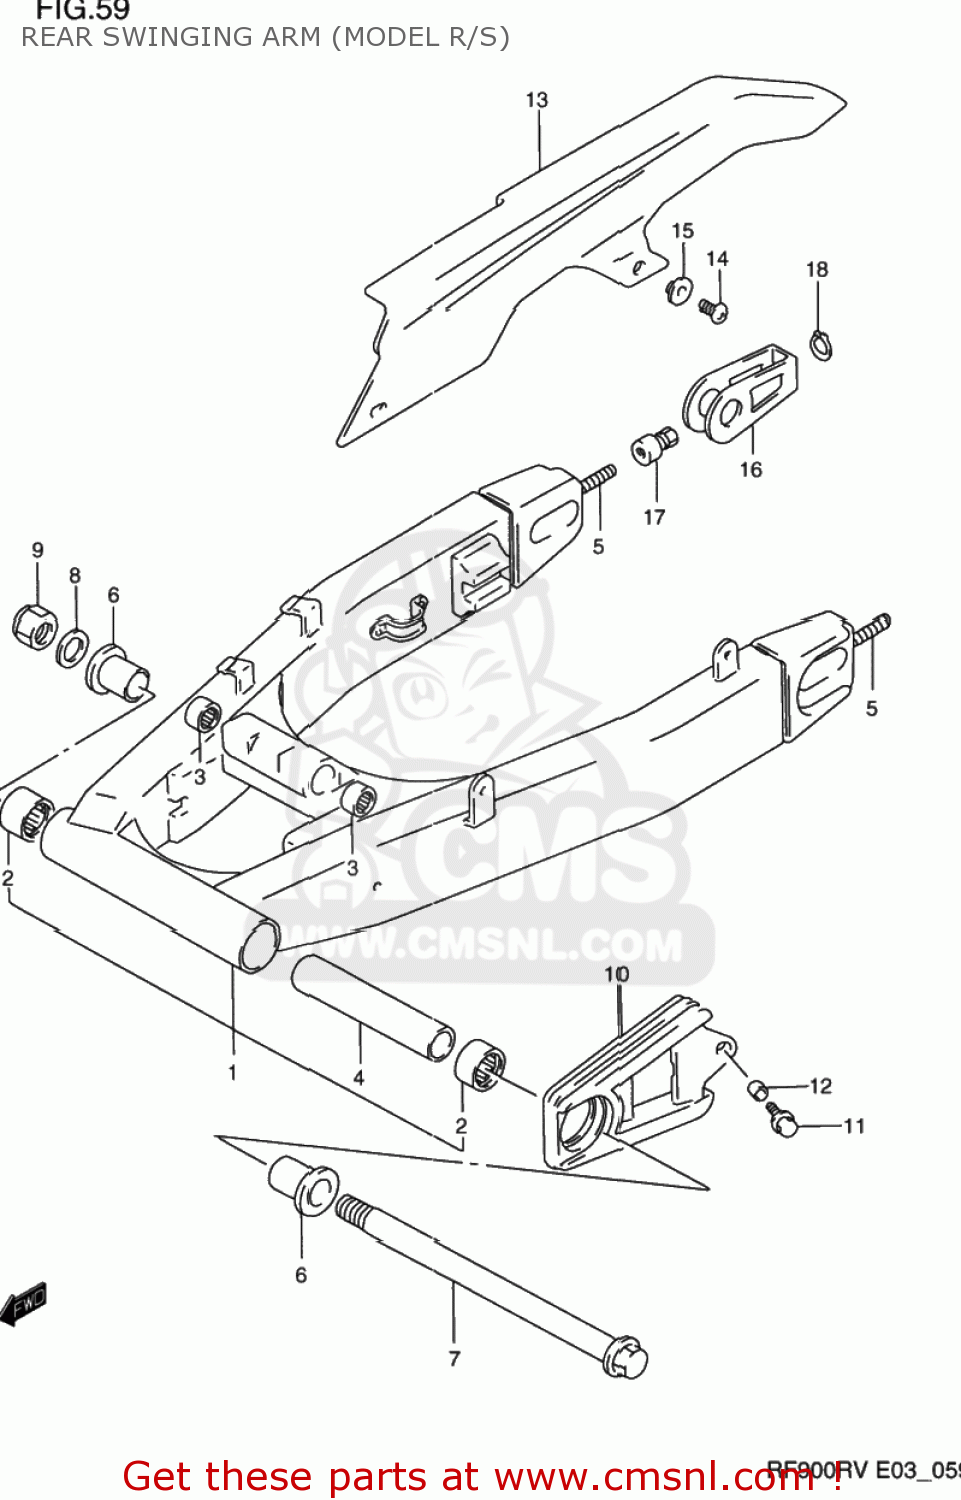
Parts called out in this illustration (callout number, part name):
1	SWINGINGARM ASSY,RR
2	BEARING(25X33X35)
3	BEARING(17X24X25)
4	SPACER,RR SWGARM PIVOT CTR
5	STUD,CHAIN ADJUSTER BOLT
6	SPACER,RR SWGARM PIVOT BERRING
7	SHAFT,RR SWINGINGARM PIVOT
8	WASHER (18.2X28X2.6)
9	NUT
10	BUFFER,CHAIN TOUCH DEFENSE
11	BOLT 6X20,WITH PLAIN WASHER
12	SPACER
13	CASE,CHAIN
14	SCREW 6X12
15	WASHER
16	ADJUSTER,CHAIN
17	ADJUSTER,CHAIN
18	CIRCLIP
